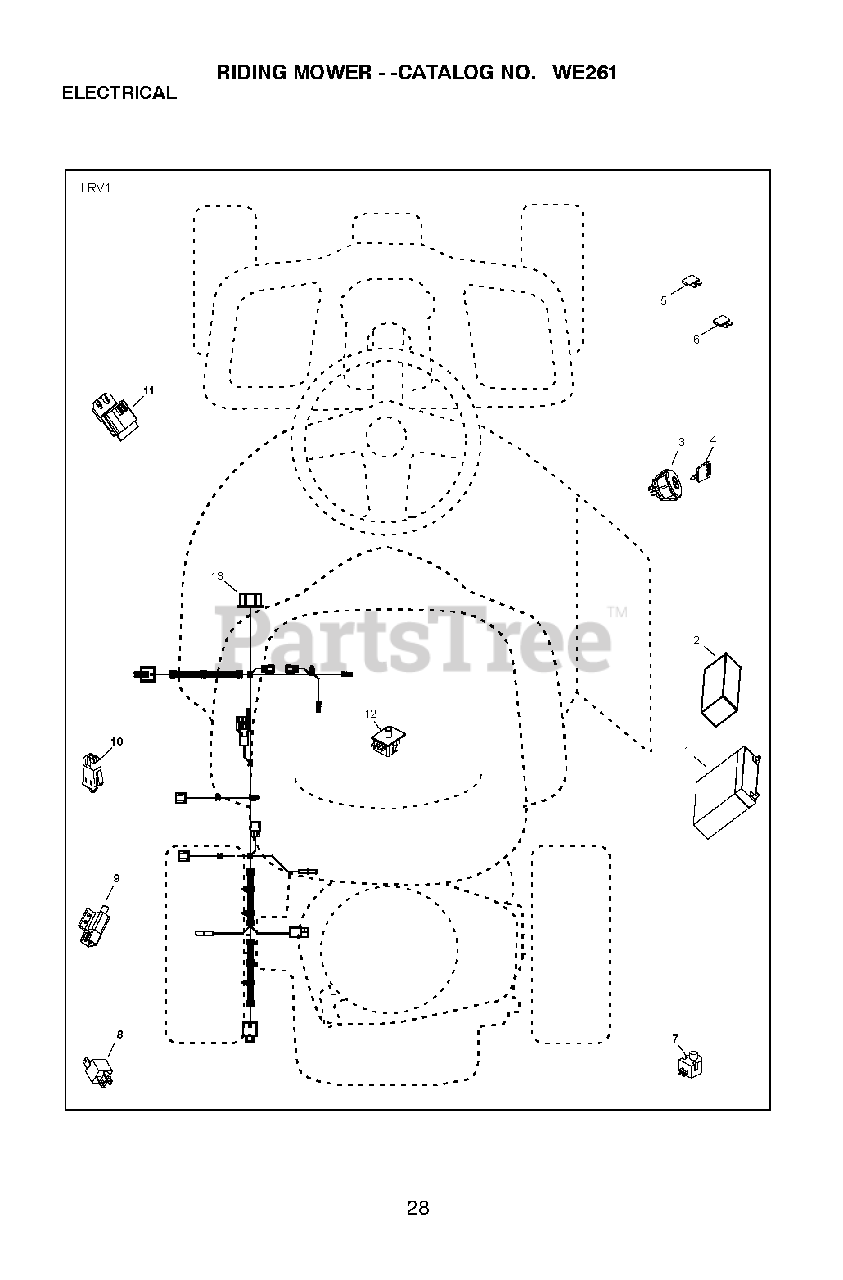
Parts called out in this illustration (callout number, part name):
1	BATTERY.2.8H.LRVA TBR
2	FOAM.POLYURETHANE
3	SWITCH.IGN.DELTA.W.LGH.ROS
4	KEY.CHAIN.BLISTER.PACK.GEN.INT
6	FUSE, 40A
7	PLUNGER SWITCH (COLOR:OLIVE)
8	RELAY, 40A
9	SWITCH INTERLOCKT
10	SWITCH INTERLOOK PUSH-IN
11	MODULE.STARTING.RECOIL.LRV
12	SWITCH.SEAT.DP W/RAMPS
13	HARNESS, IGN, ELECTSTART, LRV
